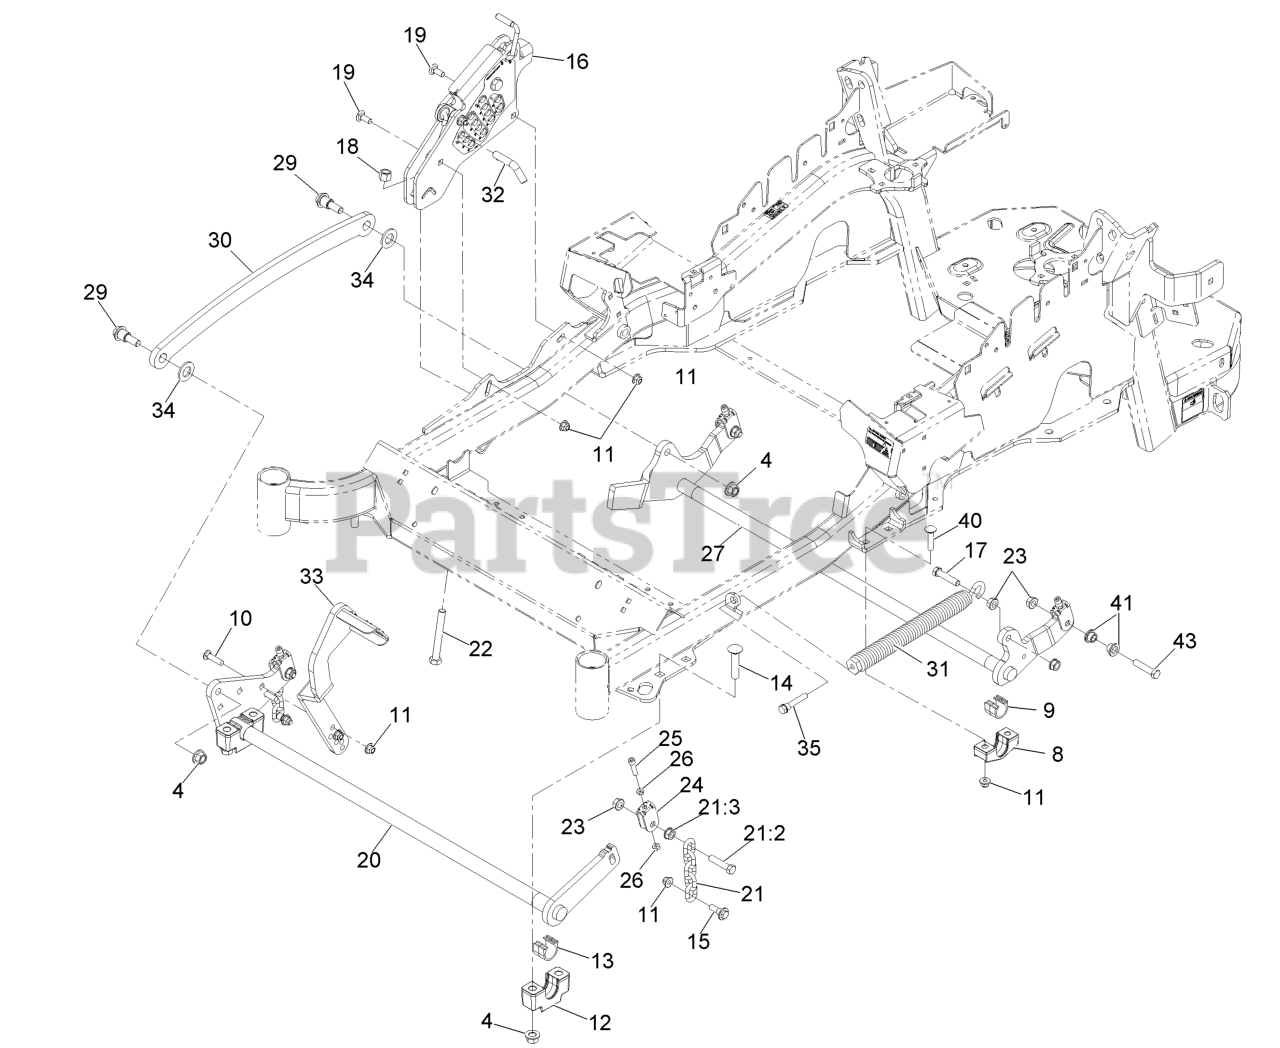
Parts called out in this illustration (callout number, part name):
4	Nut-Lock 1/2-13
9	BEARING-CROSS SHAFT, REAR
10	SCREW-CARR
11	NUT-HF, NI
12	SUPPORT-CROSS SHAFT, BEARING
13	BEARING-CROSS SHAFT, FRON
14	Bolt-Carriage 1/2-13 X 2 1/2 Spl Neck
15	SCREW-SHOULDER, HHF
16	HEIGHT-OF-CUT ASM
17	SCREW-HH
18	NUT-LOCK, NI
19	BOLT-CARR
21	DECK LIFT CHAIN ASM
21:2	SCREW-HH
22	BOLT-TAP
24	YOKE-ADJUST, DECK
25	SCREW-HSH
26	NUT-JAM
27	LIFT-DECK, REAR
29	SCREW-SHOULDER, HHF 1/2-13 X 1.12
30	LINK-LIFT, DECK
31	SPRING-EXTENSION
32	PIN-HOC
33	FOOT LEVER
34	WASHER-FLAT
35	BOLT-SHOULDER
40	SCREW-CARR
41	BUSHING-FLANGED
43	SCREW-HH
